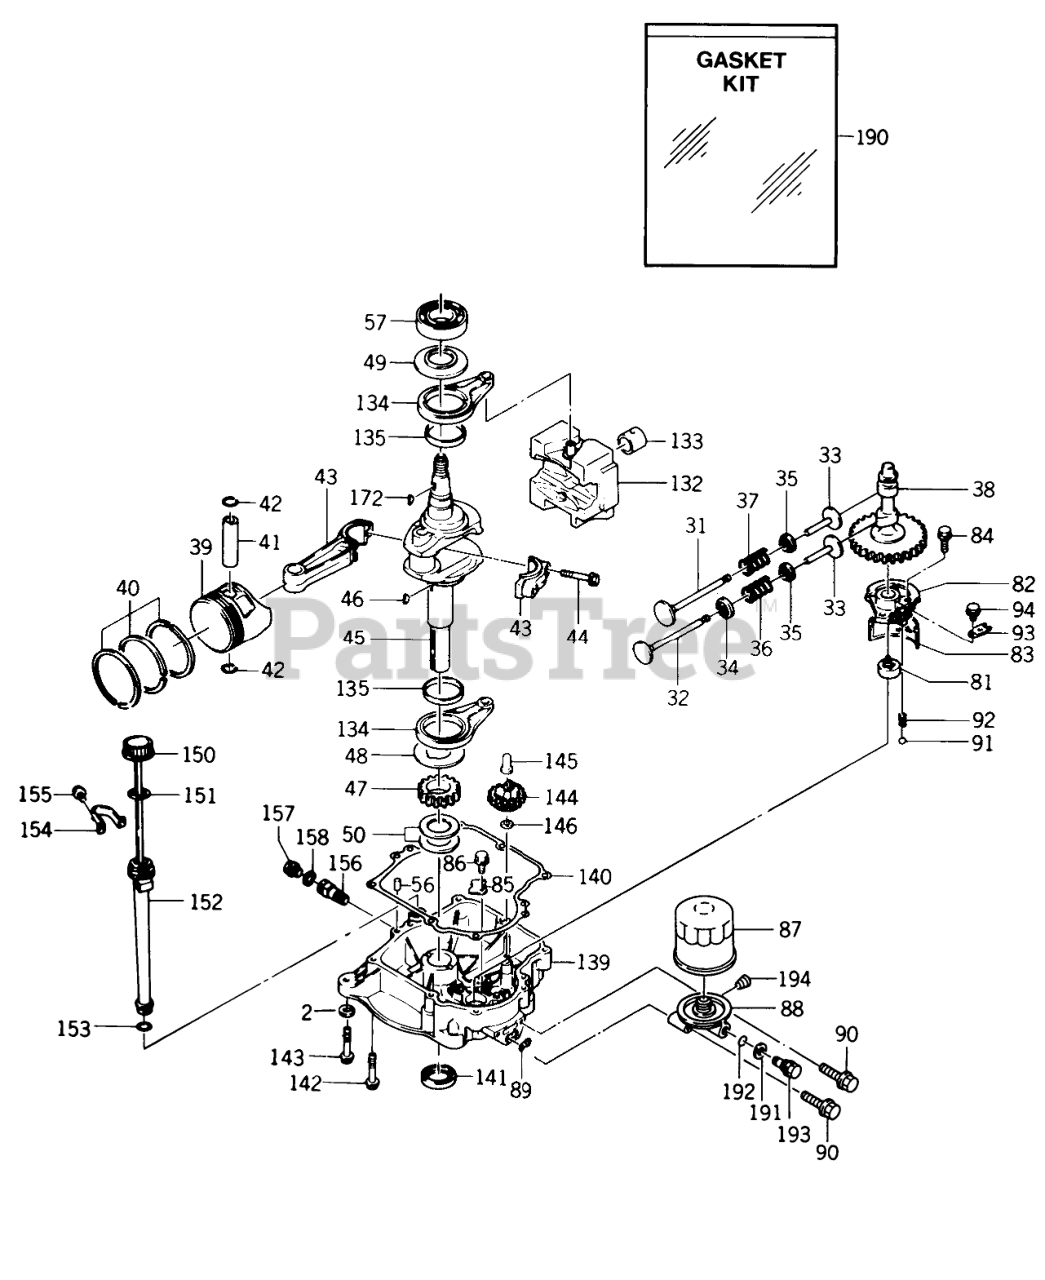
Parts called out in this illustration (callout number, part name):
2	WASHER 5/16 SAE
31	VALVE-INTAKE
32	VALVE-EXHAUST
33	TAPPET-VALVE
34	ROTATOR-VALVE
35	RETAINER-VALVE
36	SPRING-VALVE
37	SPRING-VALVE
38	SHAFT-CAM
39	PISTON-(STD)
39	PISTON-.010 OVER
39	PISTON-.020 OVER
39	PISTON-.030 OVER
40	RING (STD)
40	RING (.010 OVER)
40	RING (.020 OVER)
40	RING (.030 OVER)
41	PIN-PISTON
42	RING-SNAP
43	Connecting Rod Ass-y-Standard (includes item 44)
44	BOLT-CON ROD
45	CRANKSHAFT
46	KEY-WOODRUFF
47	GEAR-HELICAL
48	SPACER
49	SPACER
50	SHIM-T=1.18
50	SHIM-T=1.25
50	SHIM-T=1.32
50	SHIM-T=1.39
50	SHIM-T=1.46
50	SHIM-T=1.53
50	SHIM-T=1.60
50	SHIM-T=1.67
50	SHIM-T=1.74
57	BEARING-BALL #6207
81	PUMP OIL
82	COVER-PUMP
83	FILTER-INTERNAL OIL
84	BOLT, FLANGED 8X25
85	PLATE
86	Bolt
87	Filter-Oil
88	Bracket (includes item 194)
89	RING O
90	BOLT-FLANGED
91	BALL-STEEL 5/16
92	SPRING
93	PLATE
94	BOLT-FLANGED
132	Weight Complete (includes item 133)
133	BEARING-PLAIN
134	Rod Assy (includes item 135)
135	BEARING PLAIN
139	COVER-CRANKCASE
140	GASKET
141	SEAL OIL
142	BOLT-FLANGED
143	BOLT, FLANGED 8X25
144	GOVERNON
145	SLEEVE-GOVERNOR
146	WASHER
150	GAUGE-OIL
151	GASKET
152	FILLER
153	O-RING
154	CLAMP
155	Bolt
156	JOINT
157	PLUG DRAIN
158	GASKET
172	KEY-WOODRUFF
190	GASKET SET-OVERHAUL
191	GASKET
192	O'RING
194	SWITCH-OIL PRESSURE
